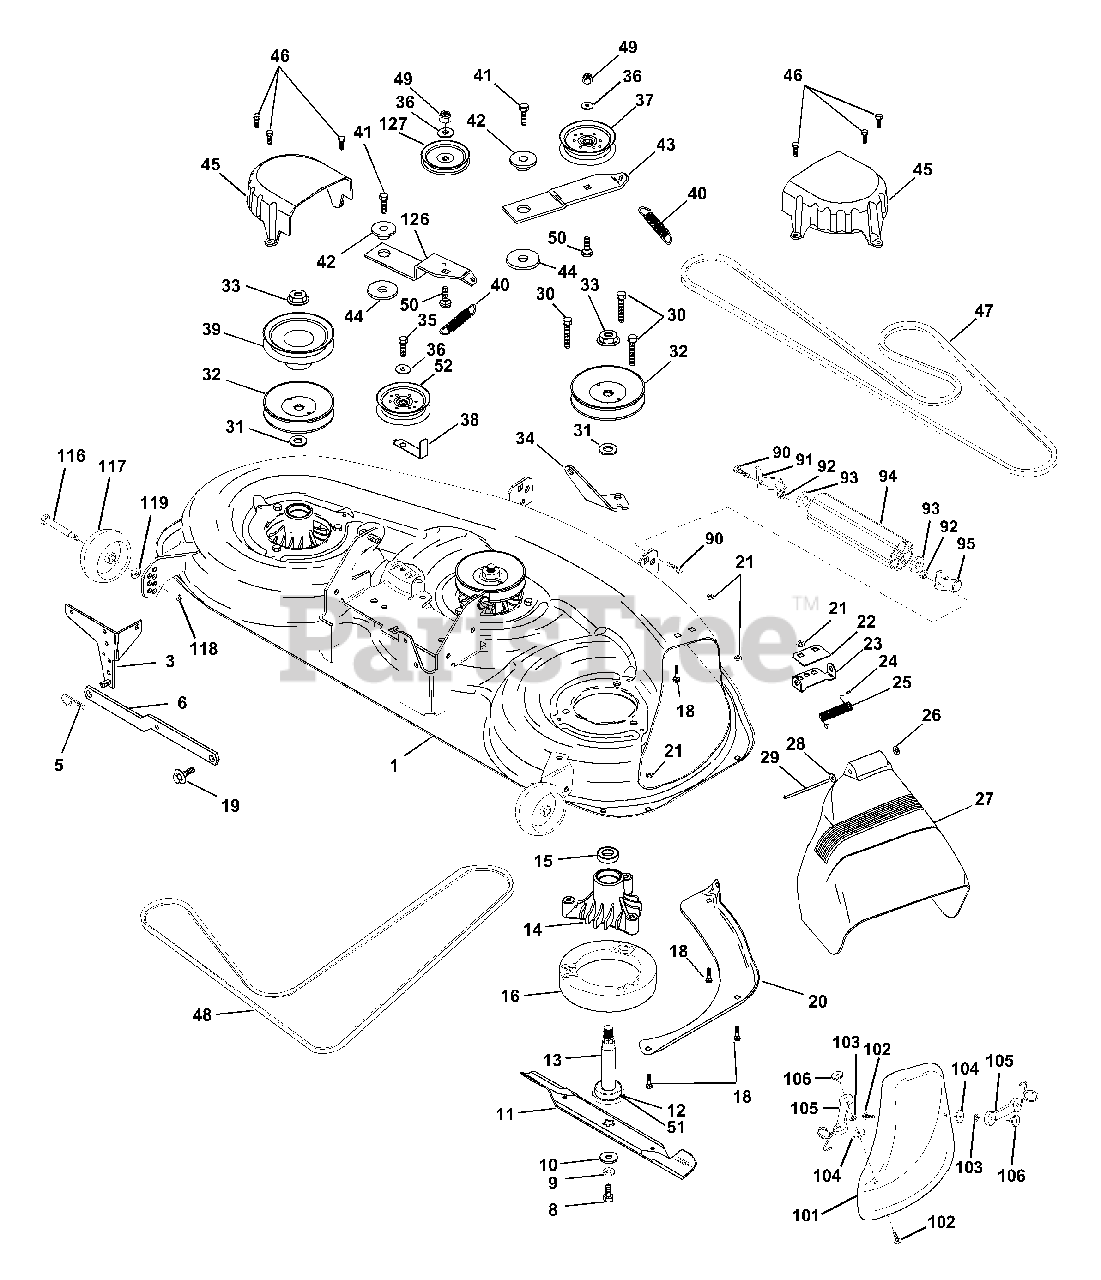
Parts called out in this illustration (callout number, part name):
1	Deck Asm., Mower 46"
3	Bracket Asm., Sway Bar
5	Retainer Spring
6	Arm, Suspension, Rear (Sway Bar)
8	Bolt, Patched 3/8-24 x 1-1/4 Gr. 8
9	Washer, Lock Hvy., Unplated 3/8
10	Washer, Hard Blade, Mower Vented
11	Blade, 46" Mower Deck
12	Bearing, Ball, Mandrel #6204
13	Shaft Asm. w/Lower Bearing
14	Housing, Mandrel
15	Bearing, Ball, Mandrel
16	Stripper, Mower Round
18	Bolt, Carriage 5/16-18 x 5/8
19	Bolt, Hex Head, Shoulder 5/16-18
20	Baffle, Vortex Mower 46"
21	Nut, Crownlock 5/16-18 UNC
22	Stiffener, Bracket
23	Bracket, Deflector
24	Cap, Sleeve
25	Spring, Torsion, Deflector
27	Shield, Deflector Mower
28	Washer 11/32 x 5/8 x 16 Ga.
29	Rod, Hinge
30	Screw, Hex Head, Thdroll
31	Washer, Spacer Mower Vented
32	Pulley, Mandrel
33	Nut, Flg. Top Lock Cntr. 9/16
34	Anchor, Spring Deck 46"
35	Screw, Thdroll 3/8-16 x 1-3/4 Tytt
36	Washer 13/32 x 13/16 x 16 Ga.
38	Keeper, Belt, Idler
39	Pulley, Idler, Driven
40	Spring, Secondary 44/46/50 Vent
41	Screw, Thdroll 3/8-16 x 1-1/4 Tytt
42	Spacer, Retainer
43	Arm, Idler Secondary
44	Washer, Hardened
45	Cover, Mandrel Deck
46	Screw, Thdroll. 1/4-20 x 5/8
47	V-Belt, Mower, Secondary
48	V-Belt, Mower, Primary
49	Nut, Crownlock 3/8-16 UNC
50	Bolt, Carriage 3/8-16 x 1-1/2 Gr. 5
51	Washer, Felt
52	Pulley Idler Flat 46 Pri Drive
90	Bolt, Fin, Hex 3/8-16 UNC x 1
91	Bracket, Asm Noseroller, LH
92	Nut, Lock, Hex w/Ins 3/8-16UNC
93	Washer 17/32 x 7/8 x 16 Ga.
94	Roller, Nose 38 & 42
95	Bracket, asm Noseroller RH
101	Cover, Mulching
102	Screw
103	Washer, Lock #10
105	Latch Asm. Bagger
106	Nut, Weld
116	Bolt, Shoulder
117	Gauge Wheel
118	Nut, Centerlock 3/8-16 UNC
119	Washer 3/8 x 7/8 x 14 Ga.
126	Arm, Idler, Primary Deck 46"
127	Pulley, Idler, V-Groove Dim. 4.25
